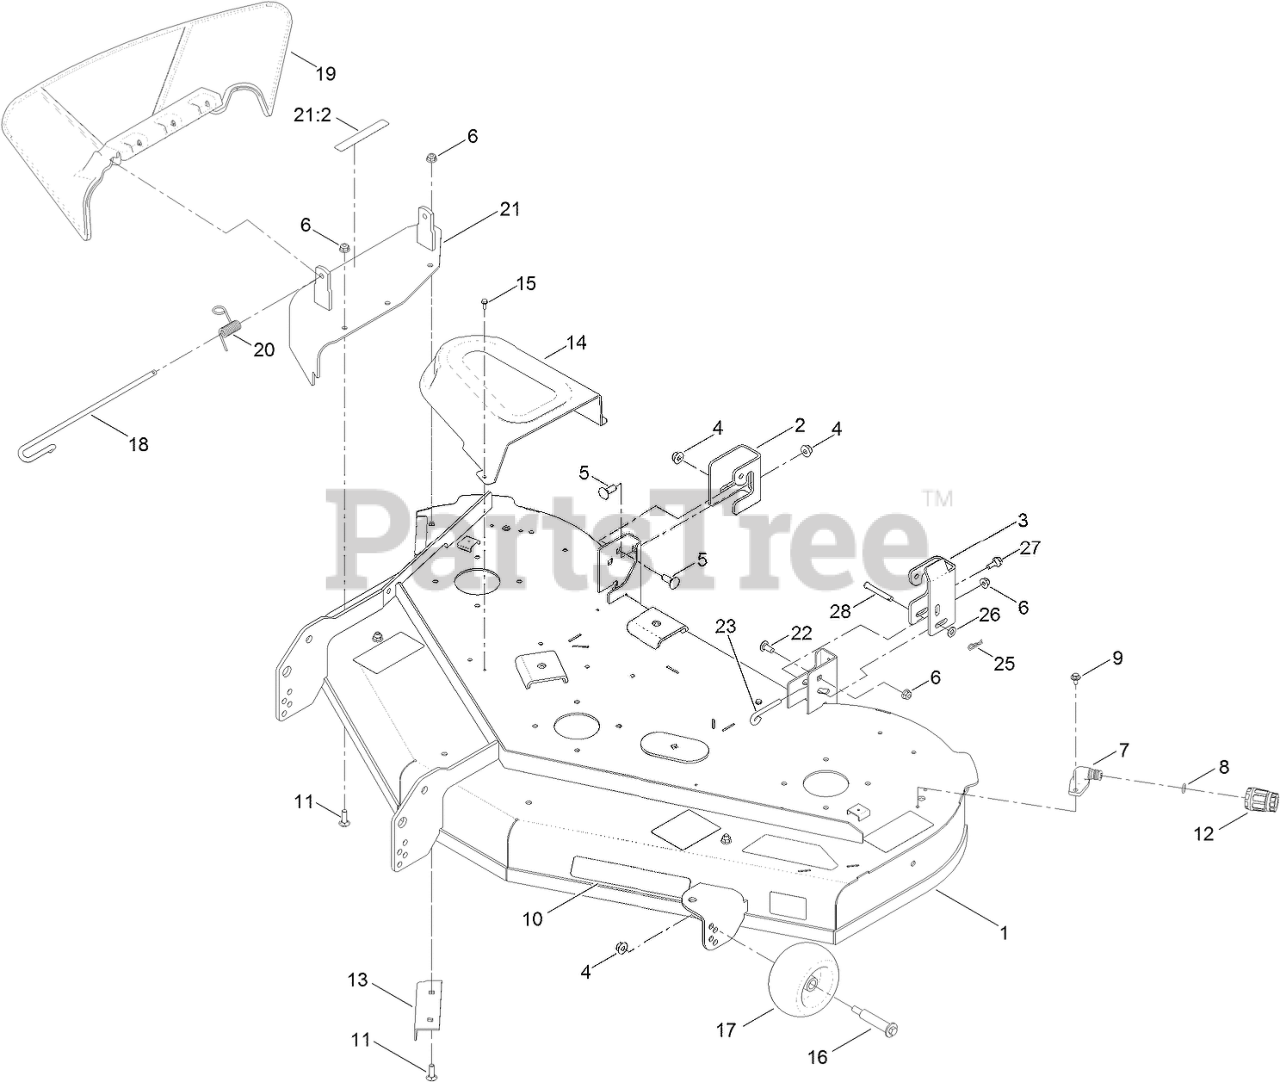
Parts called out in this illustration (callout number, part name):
1	DECK AND DECAL ASM
2	BRACKET-HANGER, RH
3	BRACKET-HANGER, LH
4	NUT-HF, NI
5	BOLT-CARR
6	NUT-HF, NI
7	FITTING-WASHOUT
8	O-RING
9	SCREW-HHFTF
10	DECAL-DECK
11	SCREW-CARR
12	CONNECTOR-HOSE
13	BAFFLE-CUTOFF
14	COVER-BELT
15	SCREW-TAPTITE
16	BOLT-SHOULDER
17	ROLLER-SCALP, ANTI
18	PIN-CHUTE
19	DEFLECTOR-DISCHARGE
20	SPRING-TORSION
21	COVER ASM W/DECAL
21:2	DECAL-DANGER
22	SCREW-CARR
23	ROD-LEVEL, DECK
25	PIN-COTTER
26	WASHER-PLAIN
27	SCREW-SHOULDER, HHF
28	PIN-CLEVIS
